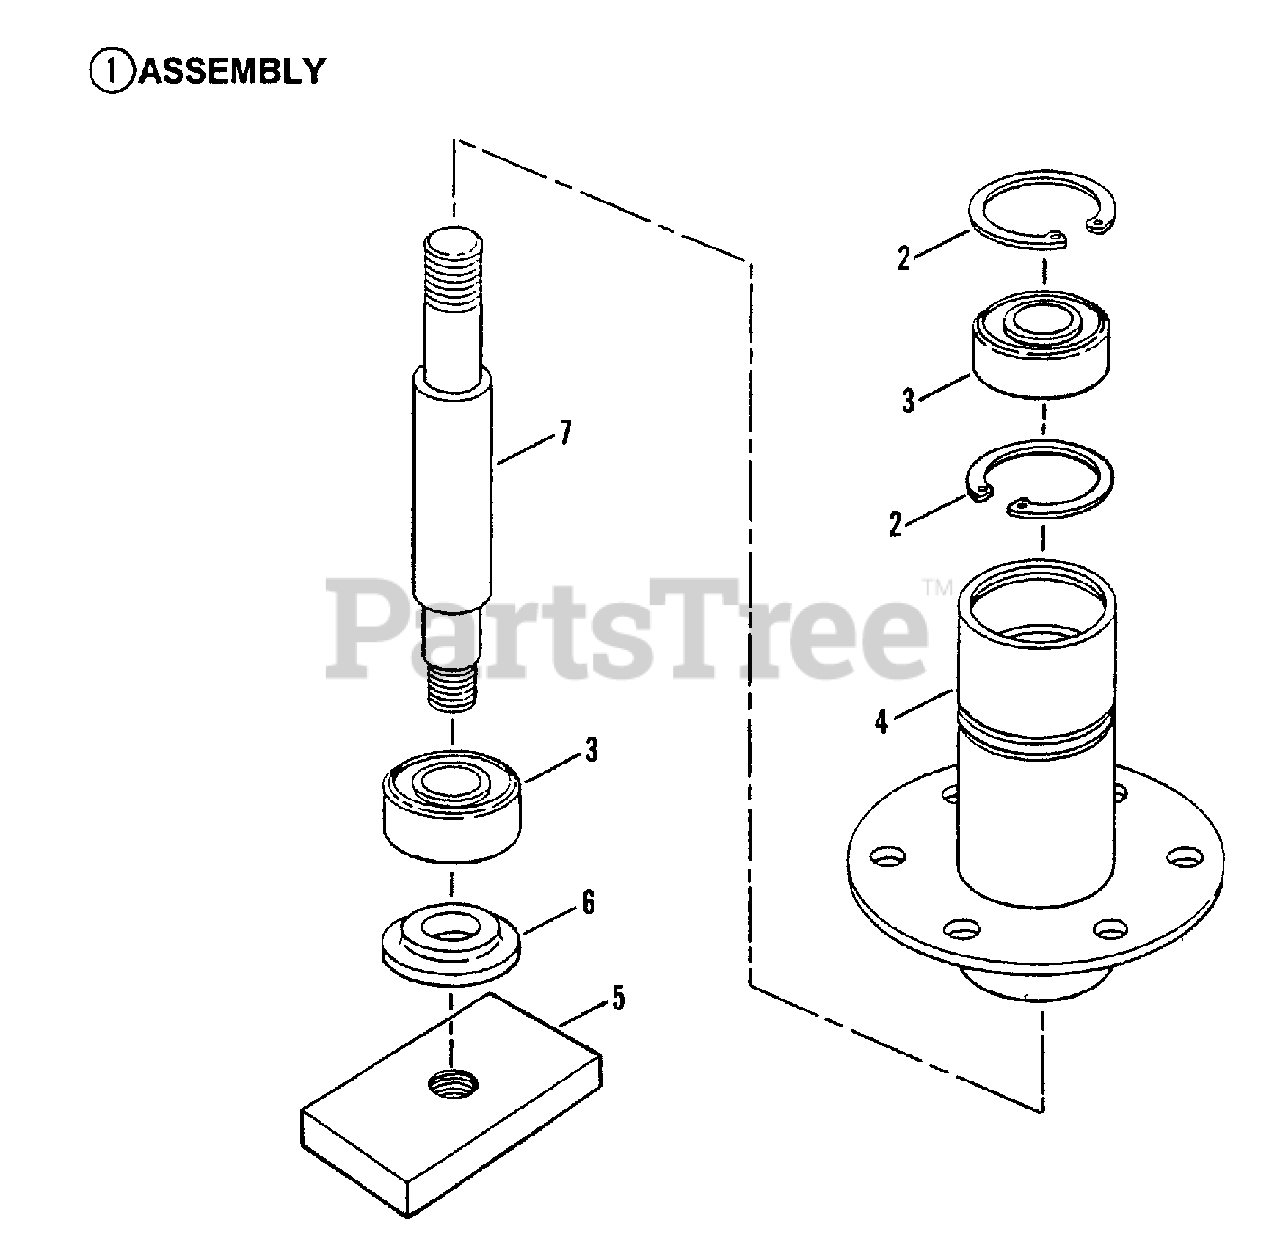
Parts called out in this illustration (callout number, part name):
1	ASSEMBLY, Spindle Housing, 42" Cutting Deck
2	RING, External Retaining 1-3/4"
3	BEARING, Spindle
4	HOUSING, Spindle
5	HOLDER, Blade
6	WASHER, Spindle
7	SPINDLE (6.5" Long)
